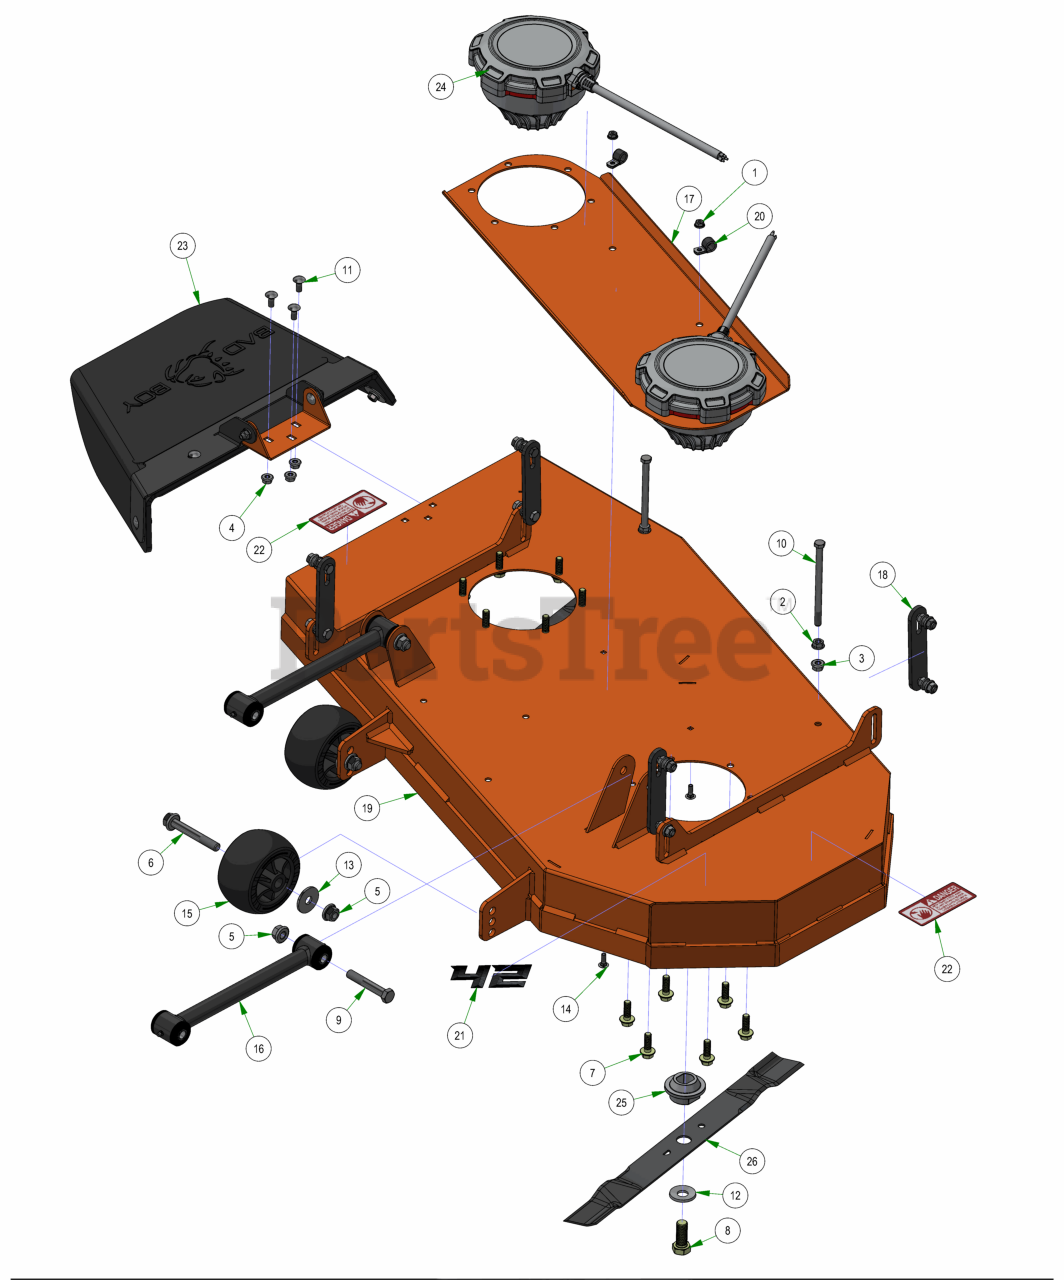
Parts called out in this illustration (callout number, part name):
1	1/4-20 NYL INSERT FLANGE LOCKNUT ZINC
2	3/8-16 HEX SERRATED FLANGE NUT HARD/ZINC
3	3/8-16 NYLON INSERT FLANGE LOCKNUT (GR.F) ZINC
4	5/16-18 NYLON INSERT FLANGE LOCKNUT ZINC
5	1/2-13 NYLON INSERT FLANGE LOCKNUT ZINC
6	1/2-13 X 90MM HEX FLANGE BOLT W/SHOULDER (GR.8) ZINC
7	M10 x 1.5mm x 30mm Flanged Hex Head Screw
8	M16 x 1.5mm x 40mm 10.9 Hex Head Screw
9	1/2-13 X 3 HEX CAP SCREW (GR.5) ZINC
10	3/8-16 X 5-1/2 HEX CAP SCREW (GR.5) ZINC
11	5/16-18 x 3/4 Carriage Bolt
12	M16 Conical Lock Washer
13	1/2 BELLEVILLE WASHER (1-5/8 OD X .140 THK) ZINC
14	1/4-20 X 3/4 CARRIAGE BOLT (GR.5) ZINC
15	Deck Wheel
16	Hybrid Turnbuckle/Deck Locator
17	Residential E Mower 42 Deck Stiffiner
18	Deck Hanger Assembly
19	Residential E Mower 42 Deck
20	1/2" ID P Clamp
21	42" Deck Decal
22	Danger Decal-Spindle/Discharge
23	MZ Discharge Chute Assembly
24	Residential E Mower Spindle Motor
25	Residential E Mower Blade Adapter
26	Residential E Mower 42 Blade
